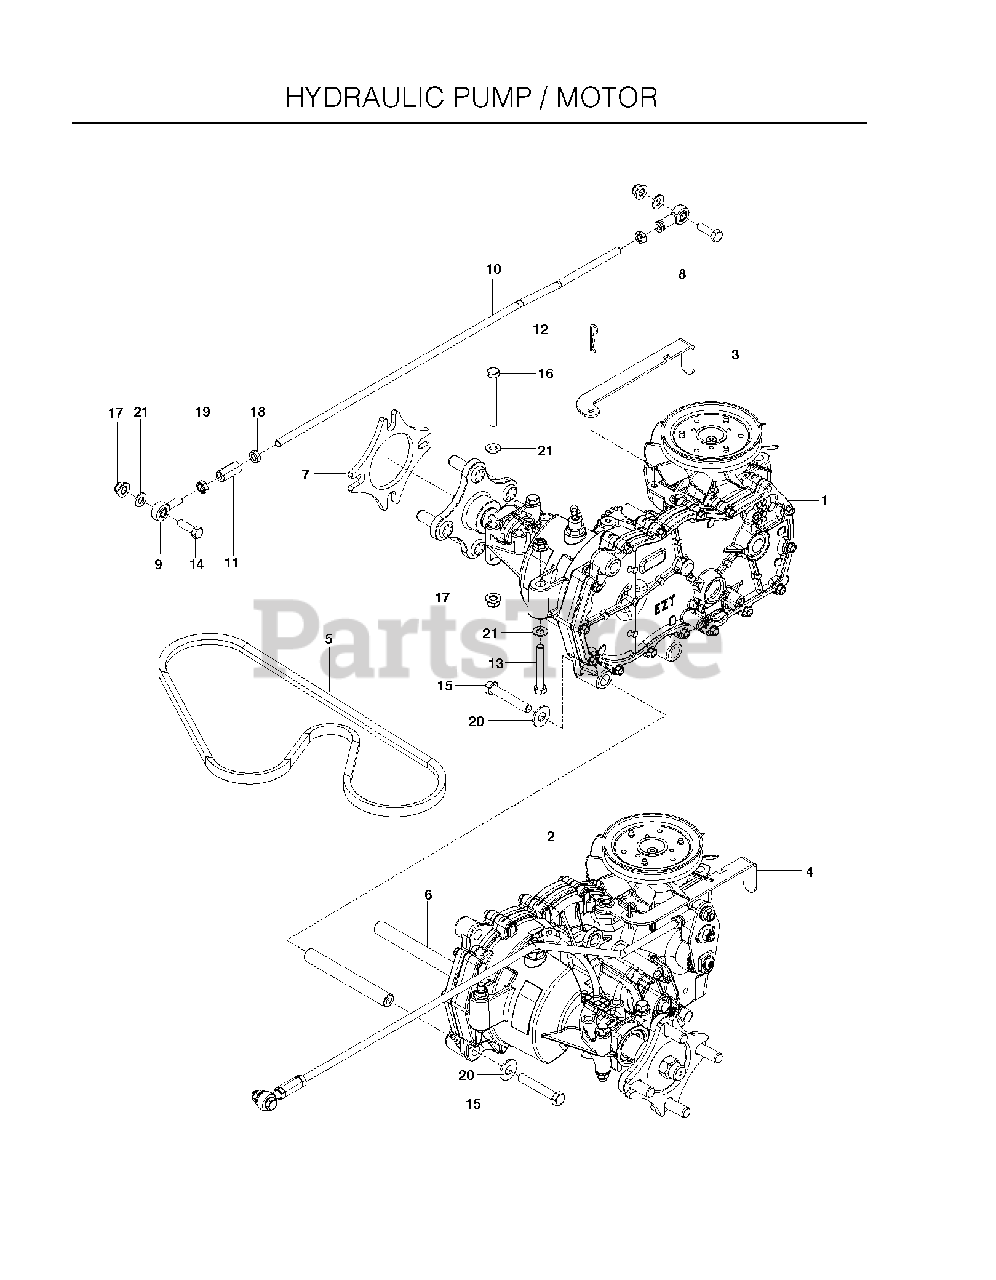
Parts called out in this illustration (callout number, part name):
1	HG_HYDRO RH
2	HG_HYDRO LH
3	RELEASE LEVER RH
4	RELEASE LEVER LH
5	BELT 30 ZEZT
6	HYDRO SPACER
7	SPACER, WHEEL
8	RH ROD END
9	ROD.END.LH
10	CONTROL ROD
11	ROD END COUPLER
12	HAIRPIN #2
13	CAPSCREW
14	HCS 5/16C X 1
15	HCS 3/8C X 2 1/4
16	HCS 5/16C X 2-3/4
17	5/16-18 NYLOC FLANGE NUT
18	NUT 5/16-24 UNF HEX JAM
19	NUT 5/16F LEFTHAND
20	WASHER 3/8 FLAT
21	FLAT WASHER 5/16 SAE
